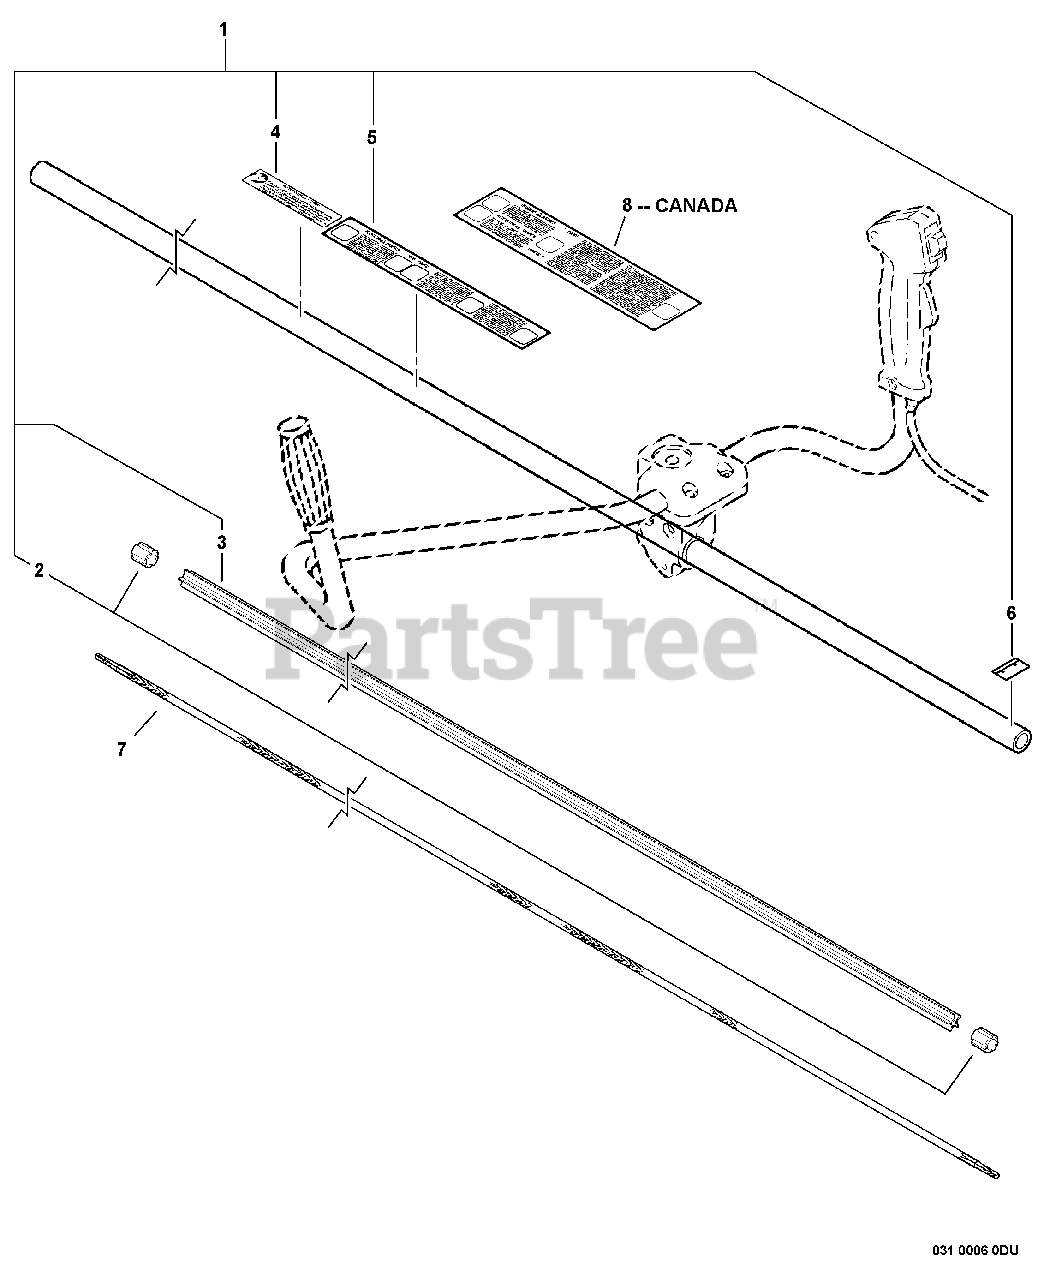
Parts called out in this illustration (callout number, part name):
1	MAIN PIPE ASSY 25×1500
3	LINER, FLEXIBLE 21.6×1420
4	LABEL, CAUTION
5	LABEL, CAUTION
6	LABEL - ALIGNMENT
7	DRIVESHAFT - FLEXIBLE L= 1522
8	LABEL, CAUTION
